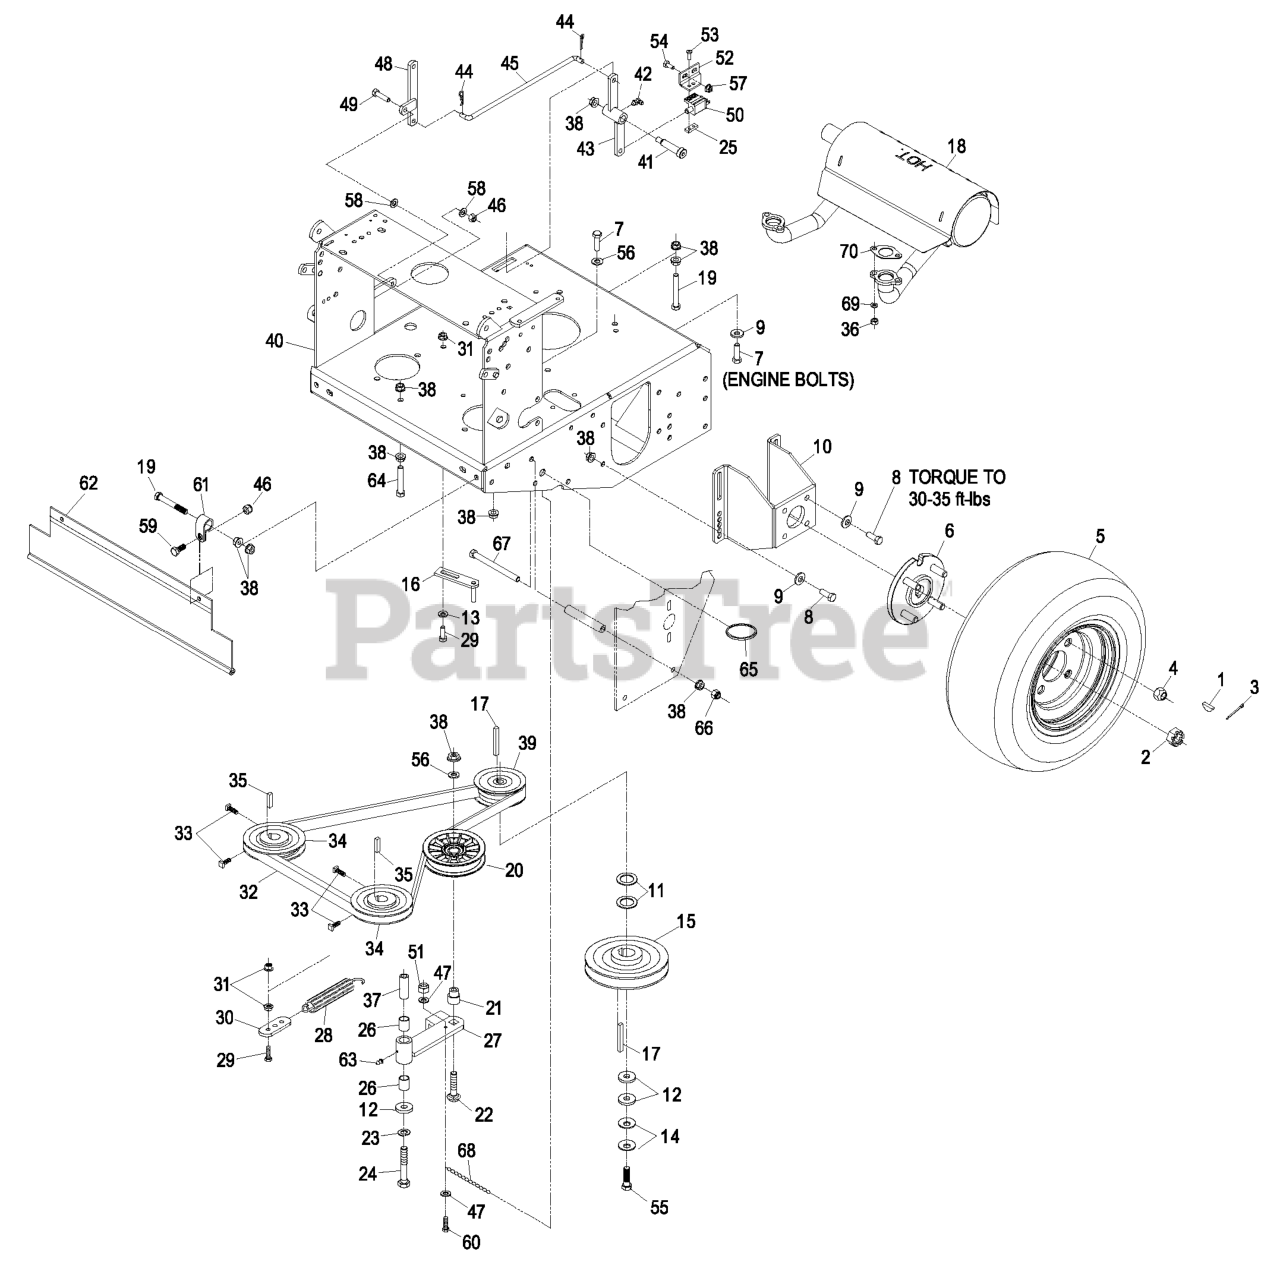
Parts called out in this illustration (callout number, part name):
1	KEY-WOODRUFF
2	NUT-HEX, SLOTTED
3	PIN-COTTER
4	NUT-LUG
5	WHEEL AND TIRE ASM
7	SCREW-HH
8	SCREW-HH
9	WASHER-BELLEVILLE
10	MOUNT-MOTOR
11	WASHER-SPACER
13	WASHER-SPRING
14	WASHER-SPRING
16	GUIDE-BELT
19	SCREW-HH
20	PULLEY-IDLER, FLAT
21	BUSHING-IDLER
22	SCREW-CARR
23	WASHER-LOCK
24	BOLT-CARR
25	PLATE-TAPPED
26	SLEEVE-BEARING
27	IDLER ARM ASM
28	SPRING-EXTENSION
29	SCREW-HH
30	ANCHOR-SPRING
32	BELT-COG
33	SCREW-SET
34	SHEAVE ASM
37	BUSHING
38	NUT-HHF, WHIZ
39	PULLEY
40	DECK,ENGINE W/DECALS
42	FITTING-GREASE, 90 DEG
43	BELLCRANK ASM
44	PIN-COTTER
45	LINKAGE-ENGAGE, BLADE
46	NUT-LOCK, NI
47	WASHER-FLAT
49	SCREW-HH
50	SWITCH-OPEN, NORMALLY
51	NUT-LOCK, NI
52	BRACKET-SWITCH, BLADE
53	SCREW-PPH
54	SCREW-HH
55	SCREW-HH
56	WASHER-FLAT
58	WASHER-PLAIN
59	SCREW-HH
60	SCREW-HSH
61	CLIP-LOOM
62	SHIELD-DRAG
63	FITTING-GREASE
64	SCREW-HH
65	RING-SPLIT
66	NUT-LOCK, NI
67	SCREW-HH
68	CHAIN-LINK, TWIST
69	WASHER-LOCK
70	GASKET-EXHAUST
